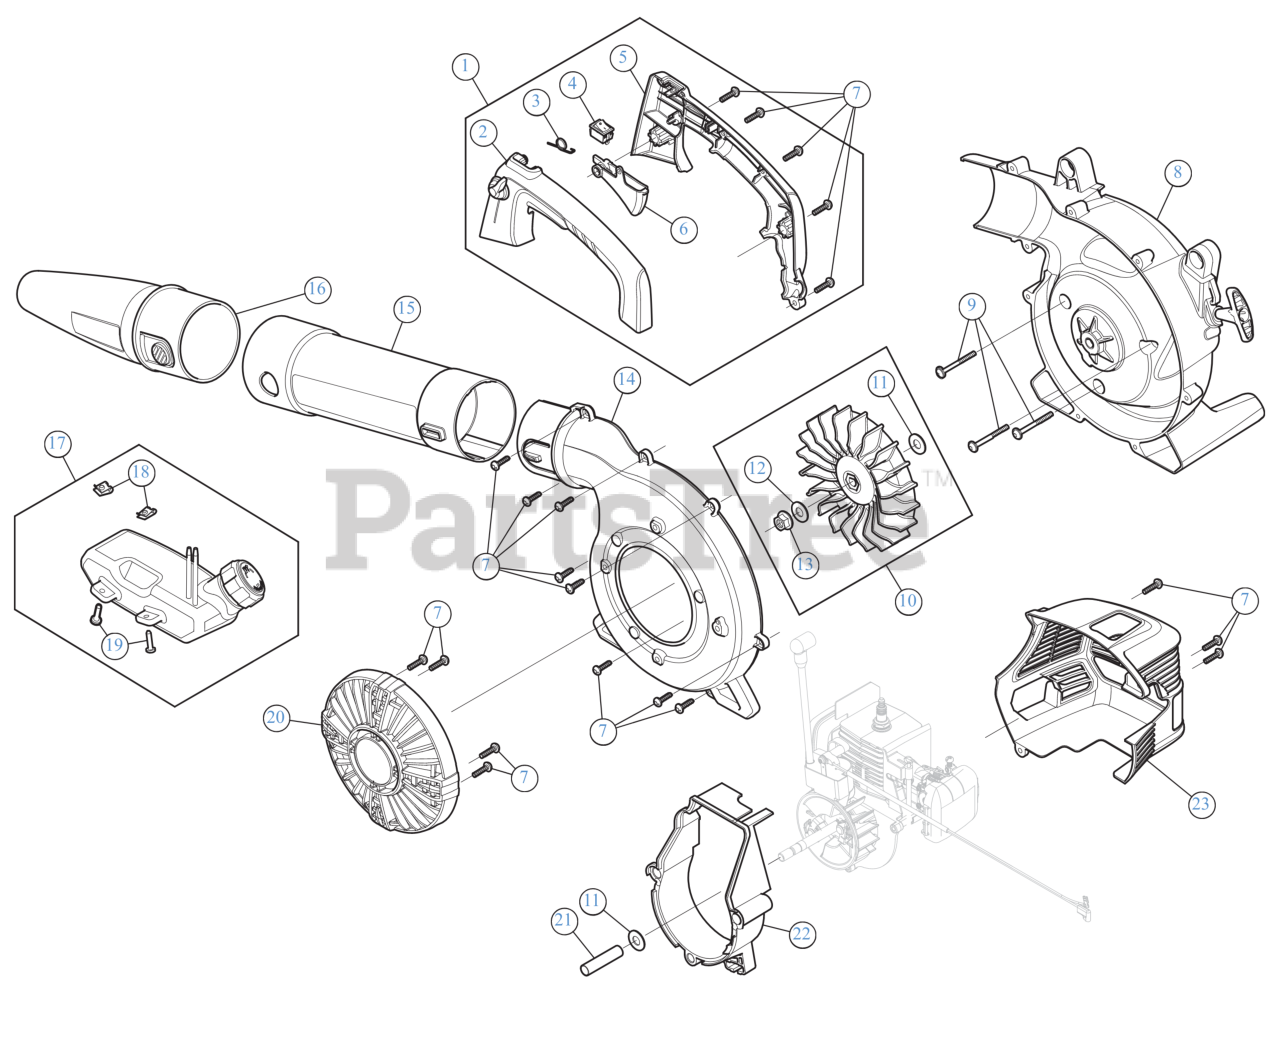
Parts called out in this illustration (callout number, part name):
1	HANDLE ASSEMBLY
2	HANDLE (lH)
3	TRIGGER SPRING
4	SW, MOMENTARY ON/O
5	HANDLE (RH)
6	THROTTLE TRIGGER
7	SCREW 8-16 x 3/4
8	IMPELLER HOUSING ASSEMBLY (INNER)
9	SCREW 10/32
10	IMPELLER ASSEMBLY
11	FLAT WASHER
12	LOCK WASHER
13	NUT 3/8-24
14	IMPELLER HOUSING ASSEMBLY (OUTER)
15	TUBE UPPER
16	NOZZLE
17	FUEL TANK ASSEMBLY
18	NUT, TINNERMAN U-T
19	SCREW:10-6 x .75
20	INTAKE COVER
21	SPACER
22	ENGINE ADAPTER
23	ENGINE COVER
